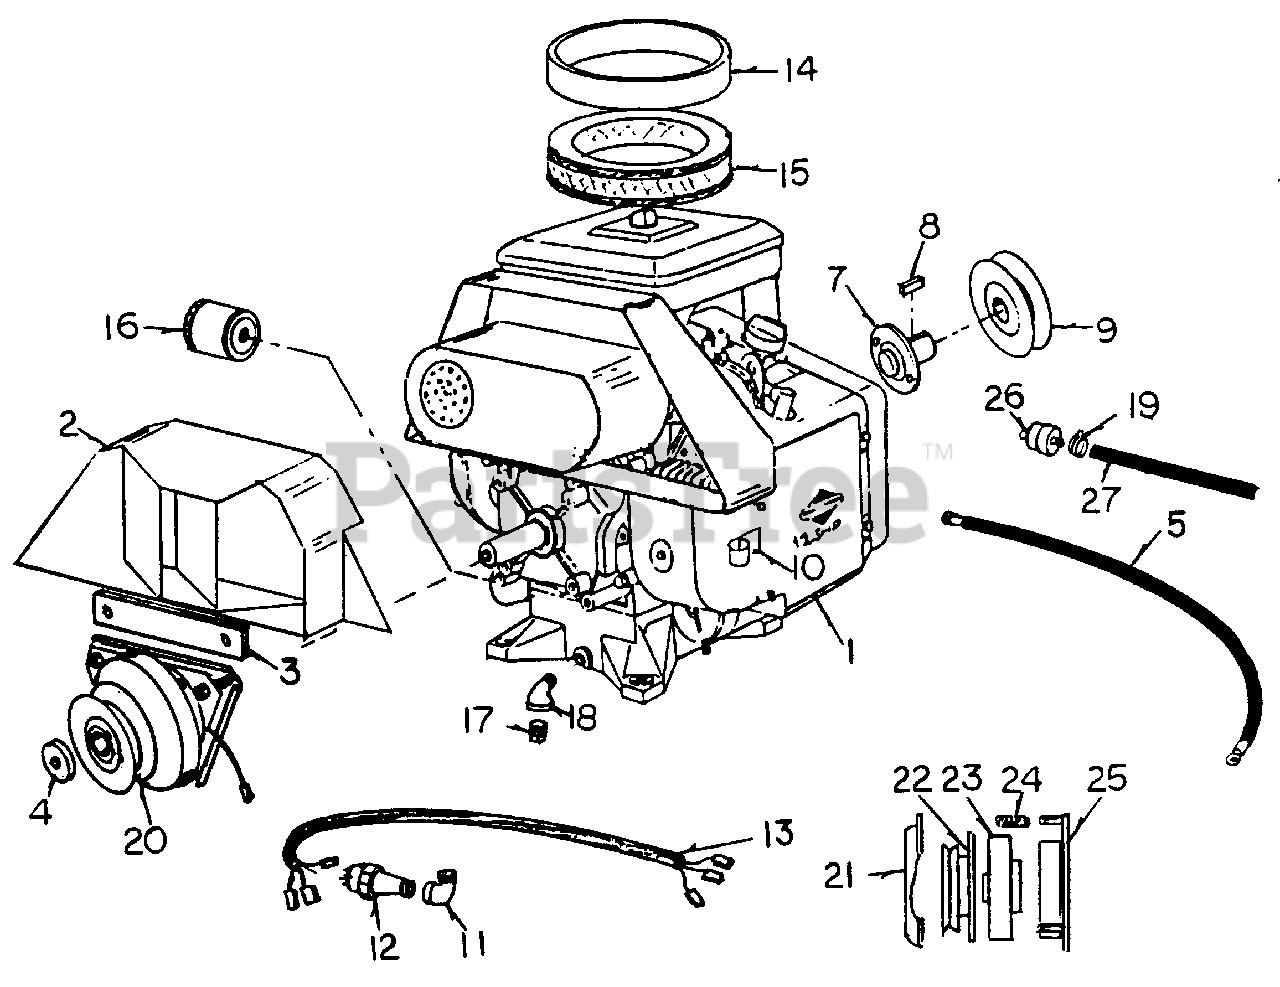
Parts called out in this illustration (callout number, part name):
1	Briggg & Stratton Twin, 12.5 HP
4	Clutch Retainer Washer
8	Key, 1/4" x 1/4" x 1"
10	Starter Cable Retainer
11	Street Elbow, 1/8" x 90ø
12	Oil Sending Unit
13	Wire Harness
14	Precleaner
15	Air Cleaner Cartrldge
16	Oi1 Filter
18	Street Elbow, 3/8"
19	Fuel Line Clamp
20	Clutch
22	Clutch Armature
23	Clutch Rotor
24	Spring & Nut Set
25	Clutch Coil
26	Fuel Filter
